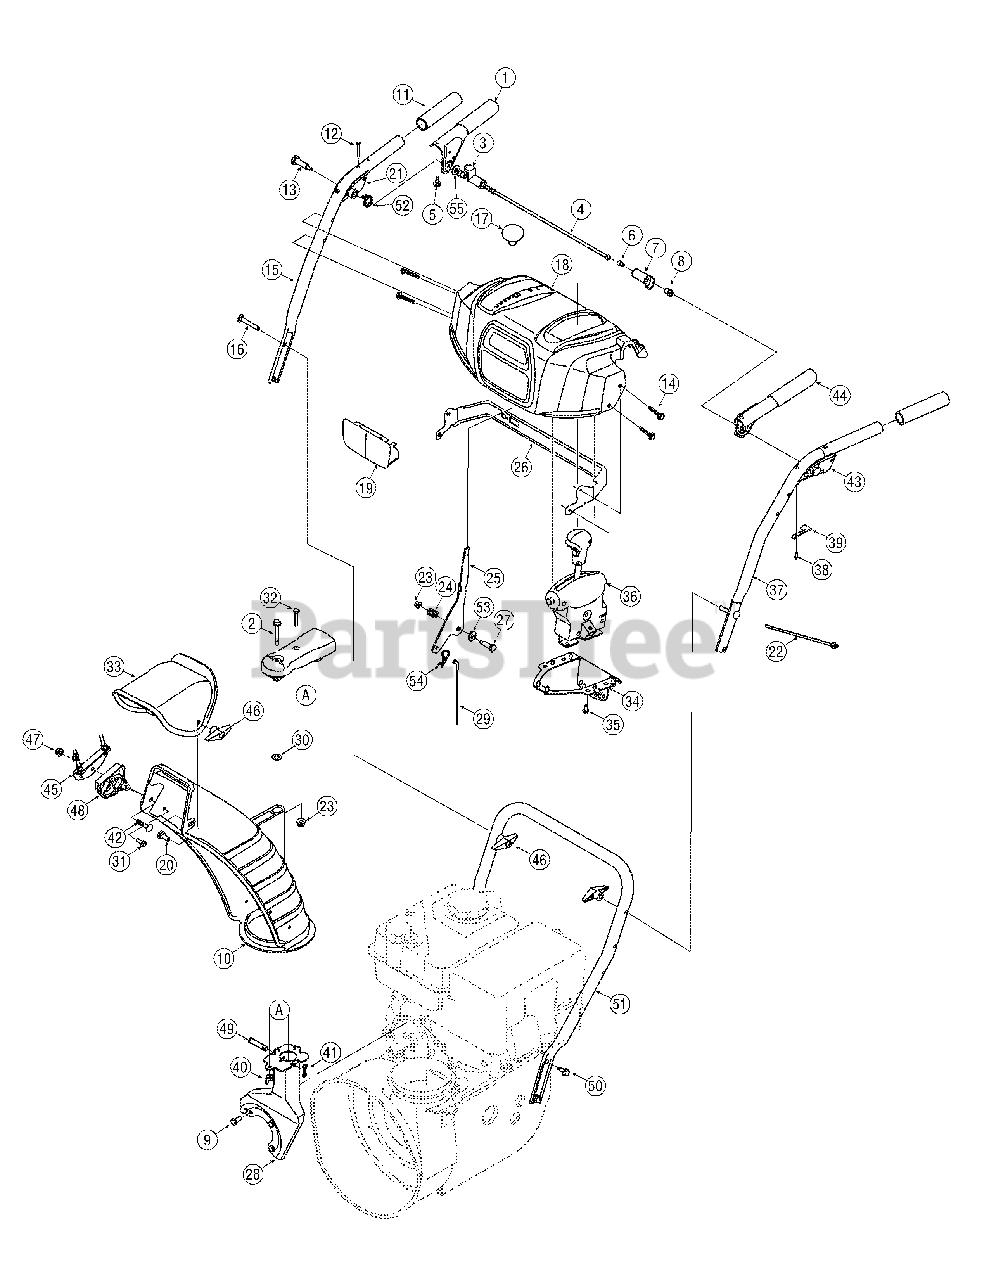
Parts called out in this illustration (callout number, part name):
1	Handle Engagement Assembly RH
2	Flange Shoulder Screw
3	Lock Plate
4	Pivot Rod
5	Rubber Bumper
6	Screw, 1/4-20 x.375
7	Clutch Lock Cam
8	Shoulder Nut, 1/4-20
9	Hex Screw, 5/16-24 x .750
10	Lower Chute
11	Handle Grip
12	Screw, #10-24 x 0.375
13	Shoulder Screw, 1/4-20 x 1.345
14	Screw, 1/4-20 x 1.625
15	Upper Handle RH
16	Carriage Screw, 5/16-18 x 2.25
17	Shift Knob
18	Handle Panel
20	Carriage Bolt, 5/16-18 x 1.0
21	Handle Clutch Lock RH Assy
22	Cable Tie
23	Flange Lock Nut, 1/4-20
24	Compression Spring
25	Shift Lever
26	Panel Bracket
27	Shoulder Screw
28	Chute Support Bracket
29	Speed Selector Cable
30	Flat Washer, .25 x .630 x .0515
31	Hi-Lo Screw, 1/4-15 x .75
32	Hex Screw, 1/4-20 x 1.50
33	Upper Chute
34	Joystick Bracket
35	Hi-Lo Screw, 1/4-15 x 0.5
36	4-Way Chute Control™ Assembly
37	Upper Handle LH
38	Screw, #8-16 x 0.50
39	Clutch Lock Spring
40	Wing Nut, 1/4-20
41	Bow Tie Cotter Pin
42	Carriage Bolt, 5/16-18 x 1.50
43	Handle Clutch Lock LH Assy
44	Handle Engagement Assembly LH
45	Cable Bracket
46	Wing Knob
47	Flange Lock Nut, 5/16-18
48	Chute Tilt Cable Guide
49	Clevis Pin
50	Screw, 5/16-18 x 0.75
51	Lower Handle
52	Torsion Spring
53	Flat Washer
54	Click Pin
55	Washer, Flat, .25 x .630 x .0515
